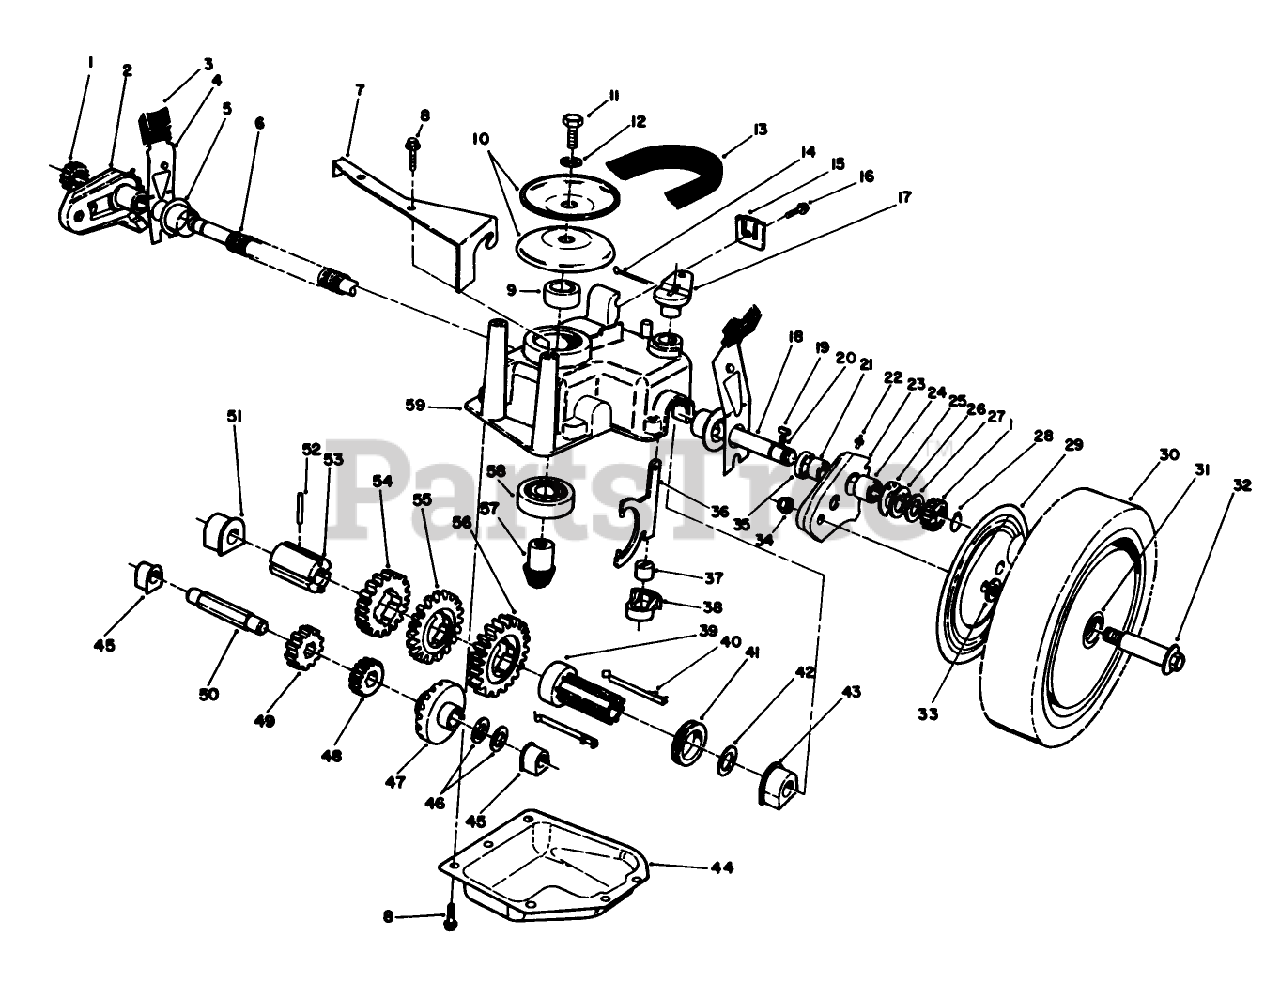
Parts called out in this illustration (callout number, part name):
1	GEAR-PINION
2	PIVOT ARM ASM RH
3	KNOB-ARM
4	SPRING ARM ASM SP
5	CAP-END
6	CONDUIT-CONVOLUTED, SPLIT
8	SCREW-HWHTF
9	SPACER
11	NUT-HEX
12	WASHER-FLAT
13	V-BELT
14	PIN-COTTER
16	SCREW-HWHTF
17	SHIFT LEVER
19	KEY RECTANGULAR
20	SPRING-COMPRESSION
21	BUSHING
22	FITTING-GREASE
26	WASHER-THRUST, OUTER
27	WASHER-THRUST, OUTER
28	PIN-ROLL
29	WHEEL COVER (RED)
31	BUSHING
32	WHEEL BOLT
33	WASHER
35	SEAL-OIL
36	YOKE-SHIFT
37	BUSHING-YOKE
38	RETAINER-FORK, SHIFT
42	Washer
43	BUSHING-OUTPUT
45	BUSHING
46	WASHER-THRUST
48	PINION-20T
49	PINION-25T
51	BUSHING
52	PIN-SPRING
53	SLEEVE-GEAR
54	GEAR-39T
55	GEAR-44T
56	GEAR-49T
58	BEARING-BALL
59	CASE-GEAR, UPPER
